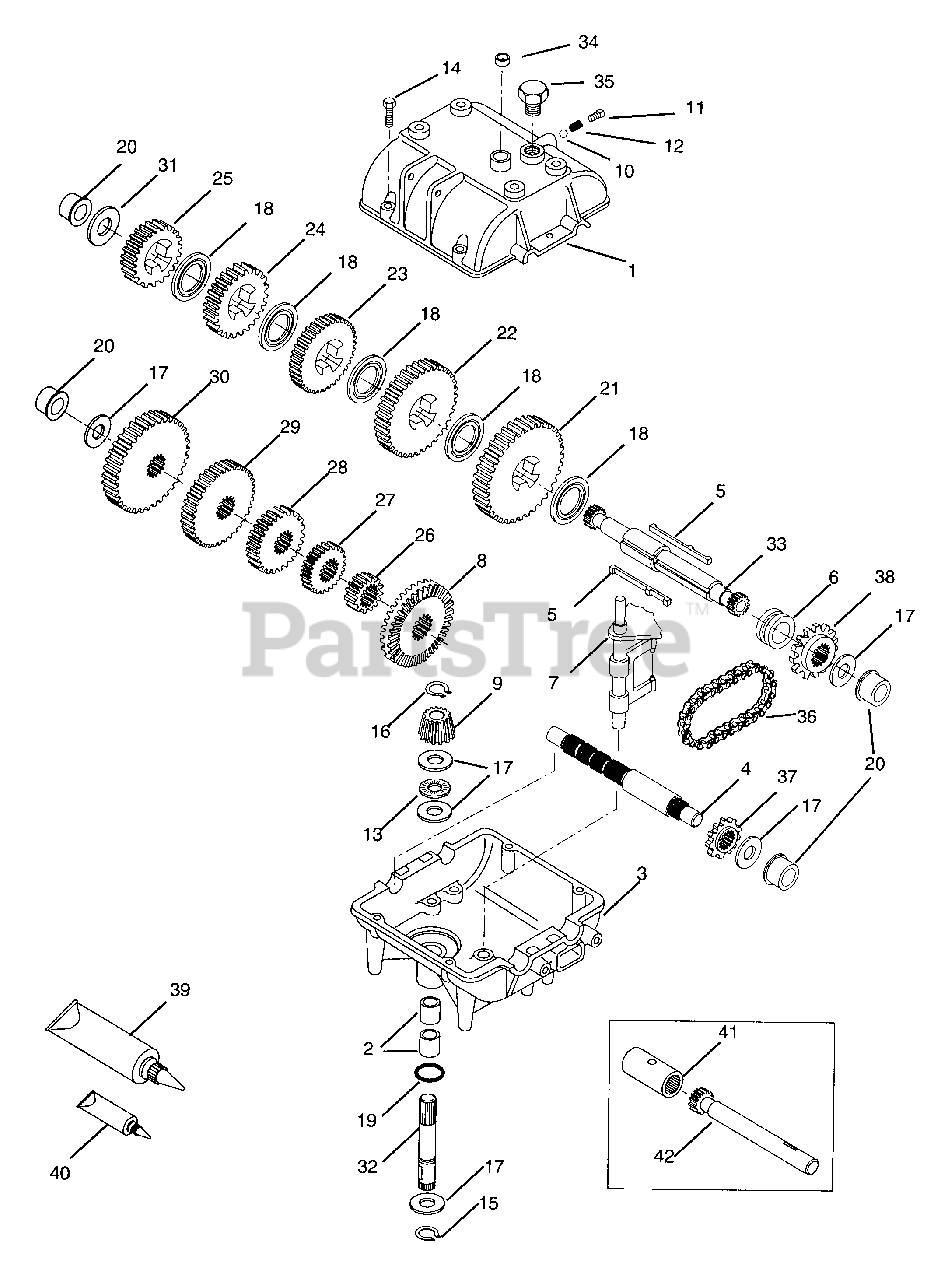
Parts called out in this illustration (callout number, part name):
1	Transmission Cover
2	Needle Bearing .625 ID x .50
2	Needle Bearing .625 ID x .75
3	Transmission Case
4	Countershaft
5	Shift Key
6	Shift Collar
7	Shift Rod & Fork Assembly
8	Bevel Gear (42 Teeth)
9	Bevel Pinion (14 Teeth-Steel)
10	Steel Ball .31 Diameter
11	Set Screw .38-16 x .38
13	Thrust Bearing
14	Screw .25-20 x 1.25
15	Ring, Retaining
16	Ring, Retaining
19	"O"-Ring
20	Bushing-Flanged
21	Spur Gear (37 Teeth)
22	Spur Gear (35 Teeth)
23	Spur Gear (32 Teeth-Steel)
24	Spur Gear (30 Teeth)
25	Spur Gear (27 Teeth)
26	Spur Gear (12 Teeth)
27	Spur Gear (15 Teeth)
28	Spur Gear (18 Teeth)
29	Spur Gear (20 Teeth)
30	Spur Gear (23 Teeth)
32	Input Shaft 3.69 long
33	Shifter and Brake Shaft
34	Square Cut Ring
35	Threaded Plug
36	Roller Chain (No. 41, 24 Links
37	Sprocket (9 Teeth)
38	Sprocket (18 Teeth)
39	Grease (32 oz. Bottle Bentonite Grease)
40	Gasket Eliminator (Loctite #515)
41	Optional Coupling (1.813 OD)
41	Optional Coupling (1.188 OD)
42	Optional Connector (6.095 long)
42	Optional Connector (6.25 long)
42	Optional Connector (6.630 long)
42	Optional Connector (7.000 long)
